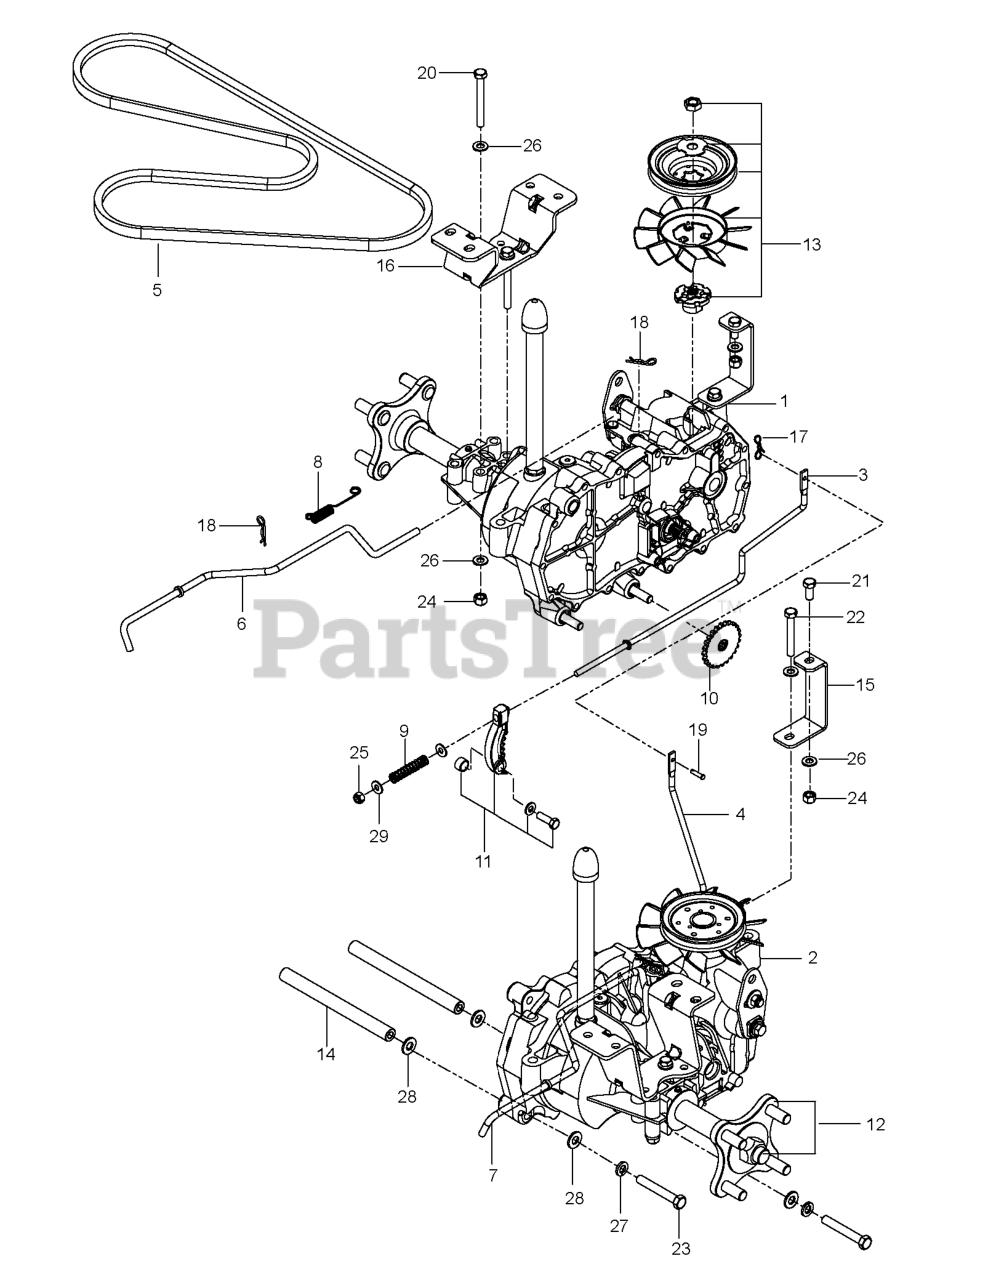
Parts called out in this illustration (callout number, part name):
1	HG_EZT, LT
2	HG_EZT, RT
3	LINKAGE.BRAKE.LT
4	LINKAGE, BRAKE RT
5	BELT, HYDRO PUMP
6	ROD.BYPASS.RZ.LH
7	ROD.BYPASS.RHT
8	SPRING.ROD.BYPASS.EZT
10	HG_DISC COG BRAKE 51635
11	HG_KIT BRAKE ARM (EZT)
12	HG_KIT, HYDRO-GEAR HUB
13	KIT FAN/PULLEY 72137
14	SPACER TUBE EZT
15	SUPPORT.FRONT.TRANS.PNTX431
16	BRACKET.EZT.MOUNT.REAR.PNTX431
17	PIN COTTER;LOCKING;BOWTIE;1IN
18	HAIRPIN #2
19	PIN.CLEVIS.3/16X.475
21	HCS 5/16C X 3/4
22	BOLT.FIN HEX 5/16-18UNC X2 1/4
23	HCS 3/8C X 2 1/2
24	NUT.71038.31-18.HEX.NYLOCK
25	NUT.1/4-20.HEX.NYLOC.ZD
26	WASHER
27	LOCKWASHER
28	WASHER
